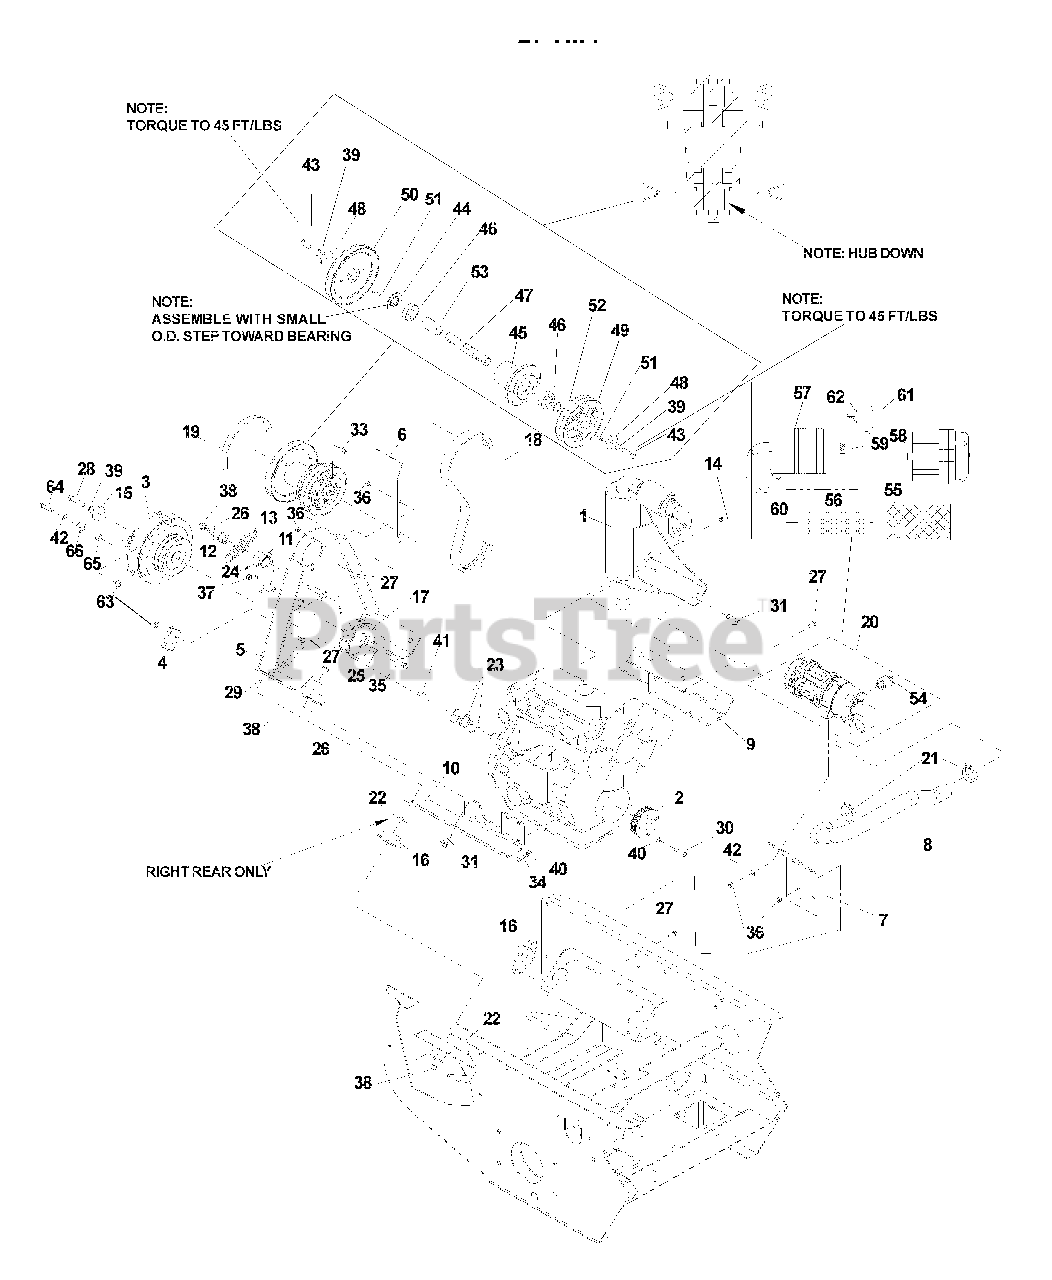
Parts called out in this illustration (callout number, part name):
2	Sheave, engine
4	Restraint
5	Jack mount
6	Shield, heat
7	Bracket, air filter
8	Air filter hose
9	Engine mount, left
10	Engine mount, right
14	Nut, M8-1.25, stover top lock
15	Washer, heavy
16	Isolator mount, engine
18	Belt, primary
19	Belt, mule
20	Air filter assembly
22	Washer, heavy
23	Bushing, machine, 1 1/8 x 10 ga.
25	Washer, 3/8, SAE
26	Washer, 1/2
27	Bolt, 5/16-18 x 3/4
28	Bolt, 7/16-20 x 2 1/2
29	Bolt, 1/2-13 x 2 3/4
30	Bolt, M8-1.25 x 35
31	Bolt, 1/2-13 x 1 1/4, serrated head
32	Bolt, 1/2-13 x 2 1/2
33	Bolt, 5/16-18 x 1
34	... Bolt, M8 x 1.25 x 20
35	Bolt, 3/8-16 x 3 1/2
36	Nut, 5/16-18, nyloc
37	Nut, 3/8-16, nyloc
38	Nut, 1/2-13, nyloc
39	Lockwasher, 7/16
40	... Lockwasher, 5/16
41	Key, 1/4 sq. x 2 1/2
42	Washer, 5/16
43	Bolt, 7/16-20 x 1 1/2
44	Combo spacer
46	Bearing
48	Washer, heavy
51	Key, 1/4" sq. x 1 1/8"
52	Machine bushing, 18 ga
54	Indicator, air filter
55	Air filter
56	Safety element
57	Body, 90°
58	Precleaner assembly
59	Mounting bracket
63	Nut, 5/16C
64	HCS, 5/16C X 1 1/4
